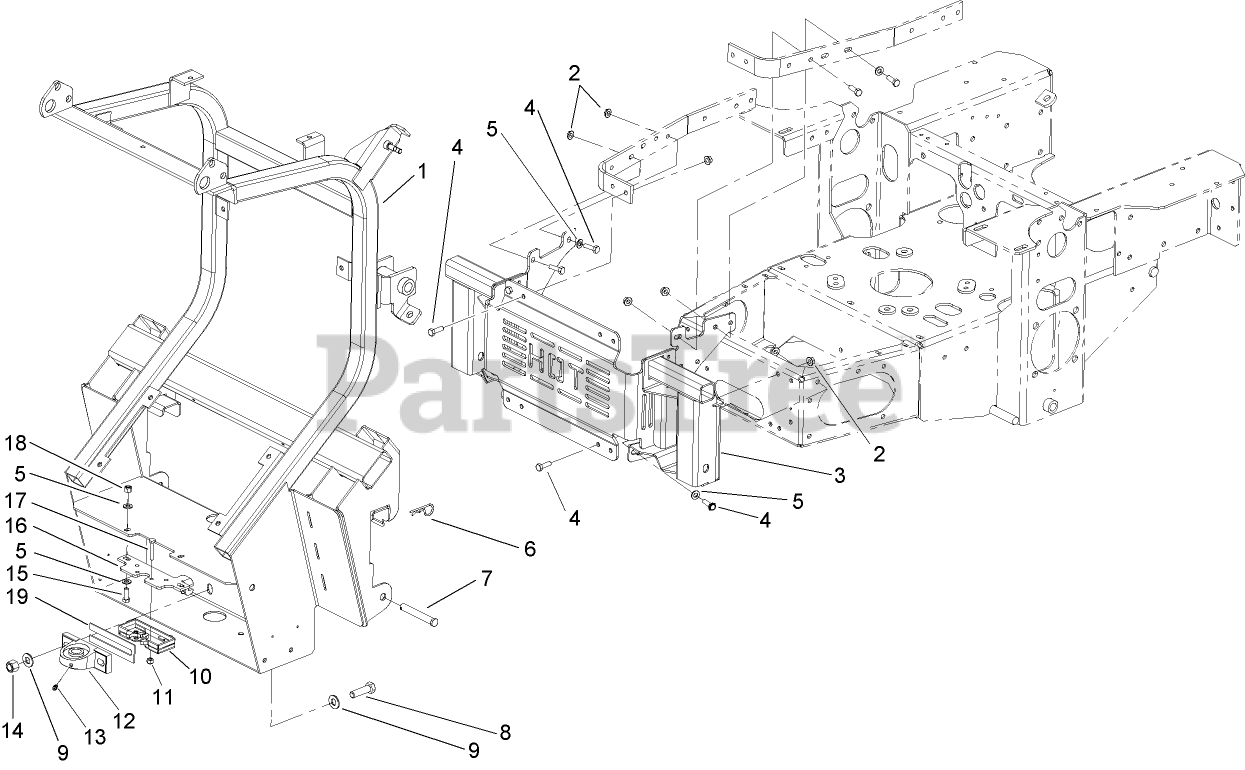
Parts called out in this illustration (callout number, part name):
1	Frame ASM
2	NUT-HF
3	Bagger Mount ASM
4	SCREW-HH
5	WASHER-PLAIN
6	PIN-COTTER
7	PIN-CLEVIS
8	SCREW-HH
9	WASHER-FLAT
10	LATCH-ROTOR
11	NUT-LOCK, NI
12	BEARING
13	FITTING-GREASE
14	NUT-LOCK, NI
15	SCREW-HH
16	BRACKET-LATCH
17	SCREW-HH
18	NUT-LOCK, NI
19	SPACER-BEARING
